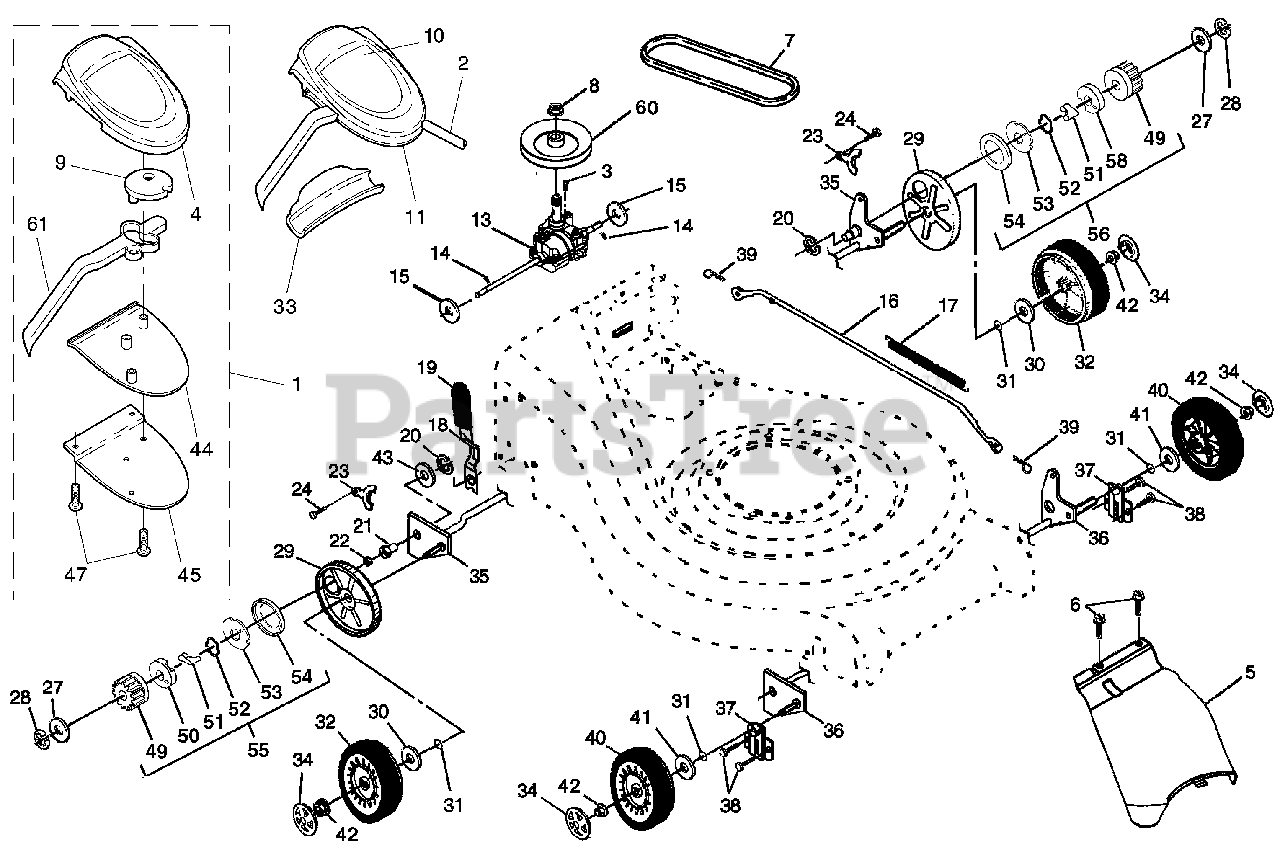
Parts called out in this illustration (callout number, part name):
1	Drive Control Assembly, Auto-Walk
2	Cable, Drive Control
4	Cover, Top, Auto-Walk Drive Control
5	Cover Drive
6	Screw, Threaded, Rolled #10-25 x .50
7	V-Belt
8	Nut, Hex, Flanglock, Zinc Plated 3/8-16
10	Decal, Drive Control
11	Decal, Drive Control Adjustment (bottom)
13	Gear Case Assembly
14	Pin, Spring, Thrust
15	Washer, Hardened
16	Rod, Connecting
17	Spring, Extension
18	Spring Selector
19	Knob, Selector Spring
20	E-Ring 7/8
21	Bearing, Support
22	Bearing, Ball
23	Retainer, Drive Assembly, Stamped
24	Screw, Tapping, Hex Head 1/4-20 x .75
27	Washer
28	E-Ring 7/16
29	Cover, Dust, Wheel
30	Washer 1/2 x 1-1/2 x .134
31	O-Ring
32	Wheel 9 x 2
33	Cap, Drive Control, Bottom
34	Hubcap
35	Shaft Assembly, Rear
36	Shaft Assembly, Front
37	Retainer, Front Shaft
38	Screw #12 x 5/8
39	Clip, Retainer
40	Wheel 8 x 2
41	Washer, Flat 3/8
42	Nut, Hex, Flangelock 3/8-16
44	Cover, Bottom, Auto-Walk Drive Control
45	Plate, Trigger, Auto-Walk Drive Control
47	Screw, Phillips Head #10 x 5/8
48	Decal, Drive Control Operation
49	Gear, Pinion
50	Retainer, Drive, RH
52	Spring, Torsion
53	Disc, Drive
54	Seal, Friction
55	Pinion/Pawl Assembly, RH
56	Pinion/Pawl Assembly, LH
58	Retainer, Drive, LH
60	Pulley, Drive
61	Lever, Auto-Walk Drive Control
